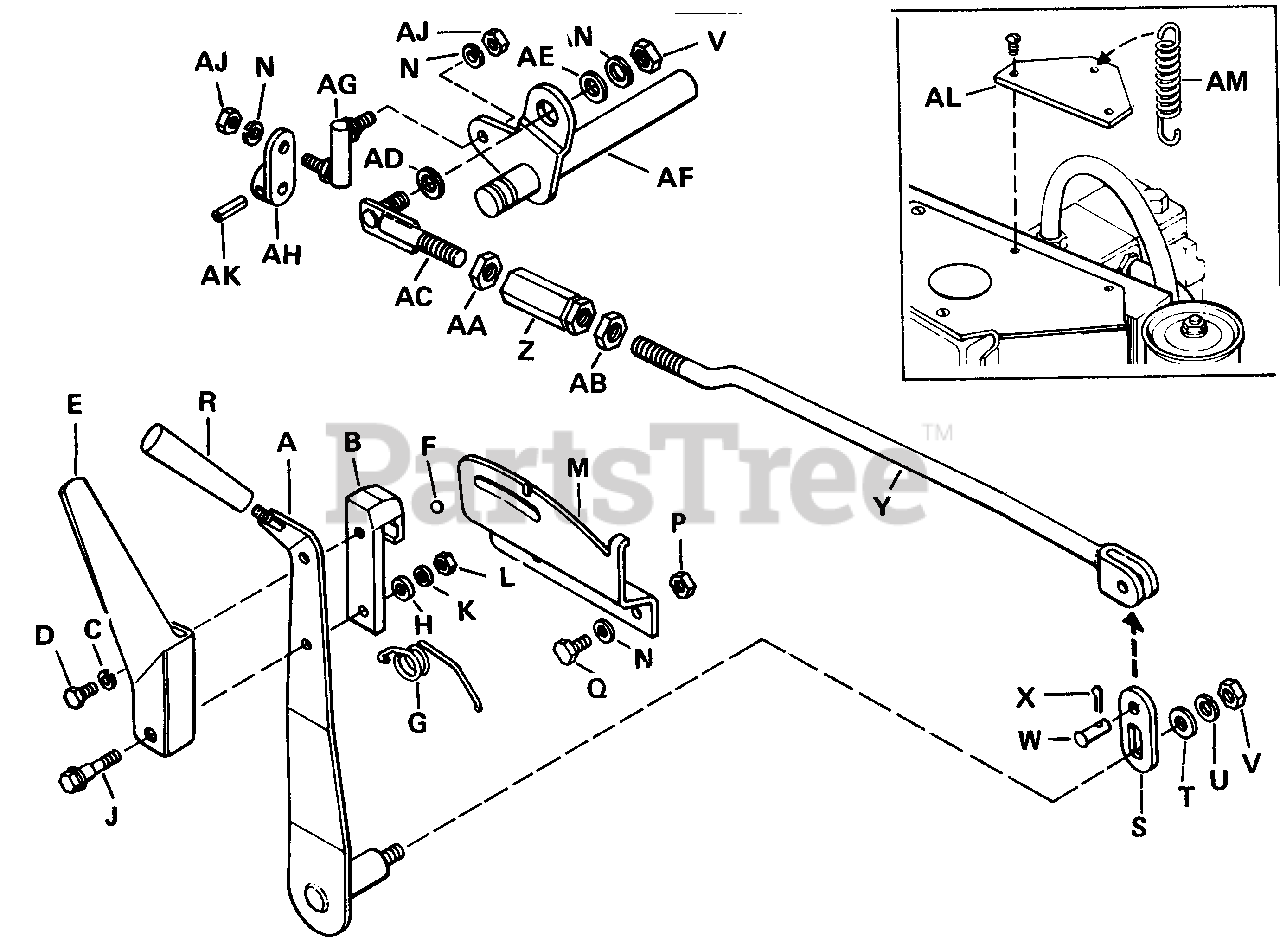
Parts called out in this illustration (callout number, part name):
A	Lever Assembly
B	Stop Clamp
C	Lock Washer, 1/4" Std.
D	Hex Capscrew, 1/4"-20 N.C. x 1/2"
F	Shift Ball Handle, 5/16"
J	Shoulder Bolt
K	Plain Washer, 1/4"
L	Full Hex Lock Nut, 1/4"-20
M	Support Plate
N	Lock Washer, 5/16"
P	Full Hex Nut, 5/16"-18
Q	Hex Capscrew, 5/16"-18 N.C.x 5/8"
T	Plain Washer, 3/8"
U	Lock Washer, 3/8"
V	Full Hex Nut, 3/8"-16
X	Cotter Pin, 3/32" x 3/4"
Y	Rod Assy., Control, Front
Z	Turn Buckle
AA	Full Hex Nut, 7/16"-14 L.H.
AB	Full Hex Nut, 7/16"-14 R.H.
AC	Rod Assy., Rear Control
AE	Plain Washer, 5/16"
AF	Shaft Assy., Control
AG	Ball Joint, Double End
AH	Link Assy., Control
AJ	Full Hex Nut, 5/16"-24
AK	Roll Pin, 1/4" x 1-1/4"
AL	Spring Clip
